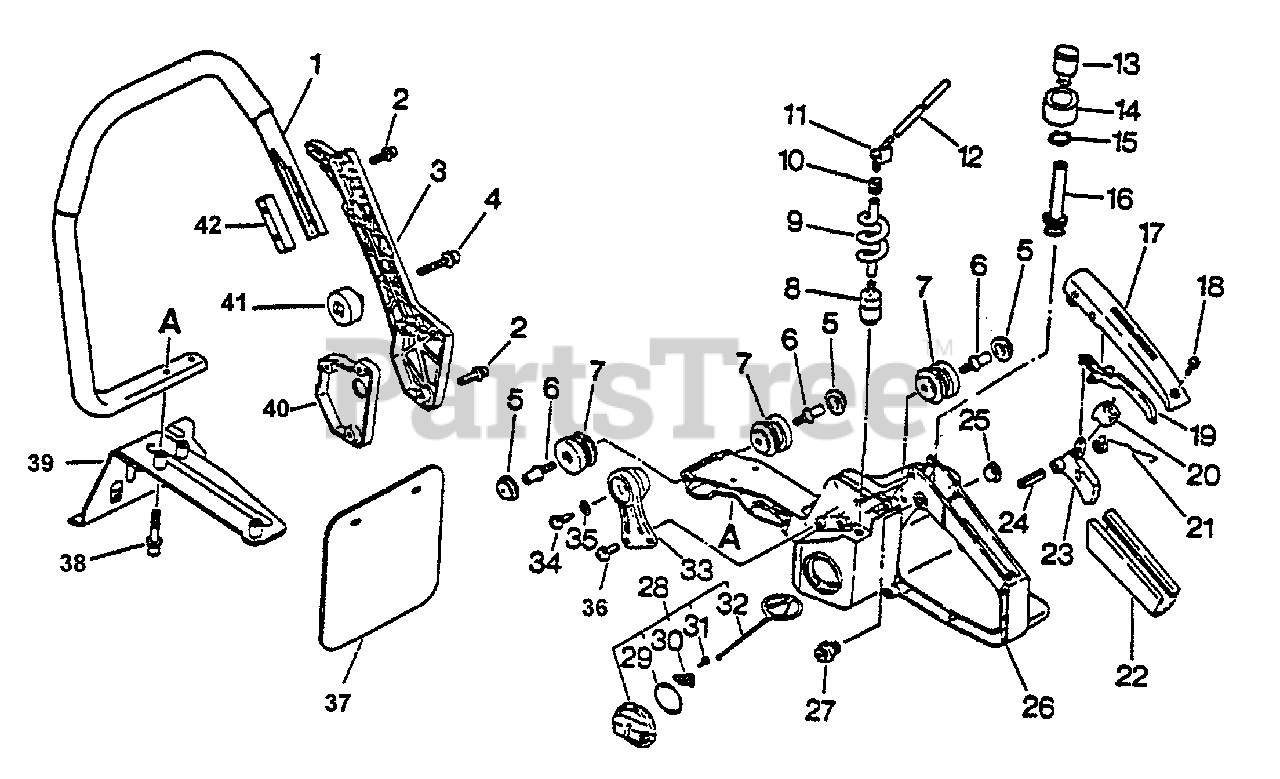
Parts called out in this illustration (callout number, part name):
1	HANDLE - FRONT
2	SCREW - 5X35
3	SUPPORTER, FRONT HNDL. KIT
4	SCREW - 5X30
5	CAP, CUSHION
8	FILTER, FUEL
9	PIPE - BLACK
10	GROMMET
11	CONNECTOR, PIPE
12	PIPE - FUEL
13	VENT, FUEL TANK
14	COVER, VENT
15	CLIP - 5.5
16	PIPE - VENT
17	COVER, HANDLE
18	SCREW - 4X14
19	LOCKOUT, THROTTLE
21	SPRING, TRIGGER
22	GRIP, HANDLE
23	TRIGGER, THROTTLE
24	PIN - SPRING -- 5X25
26	HANDLE - REAR
27	LATCH, THROTTLE
28	CAP ASSY
29	O-RING - 29
30	RETAINER
31	SCREW - 3X8
32	CONNECTOR, CAP
34	SCREW - 5X14
35	WASHER - 5
36	SCREW - 5X14
37	SHIELD
38	SCREW - 5X30
39	FIXTURE, HANDLE
40	SPACER
